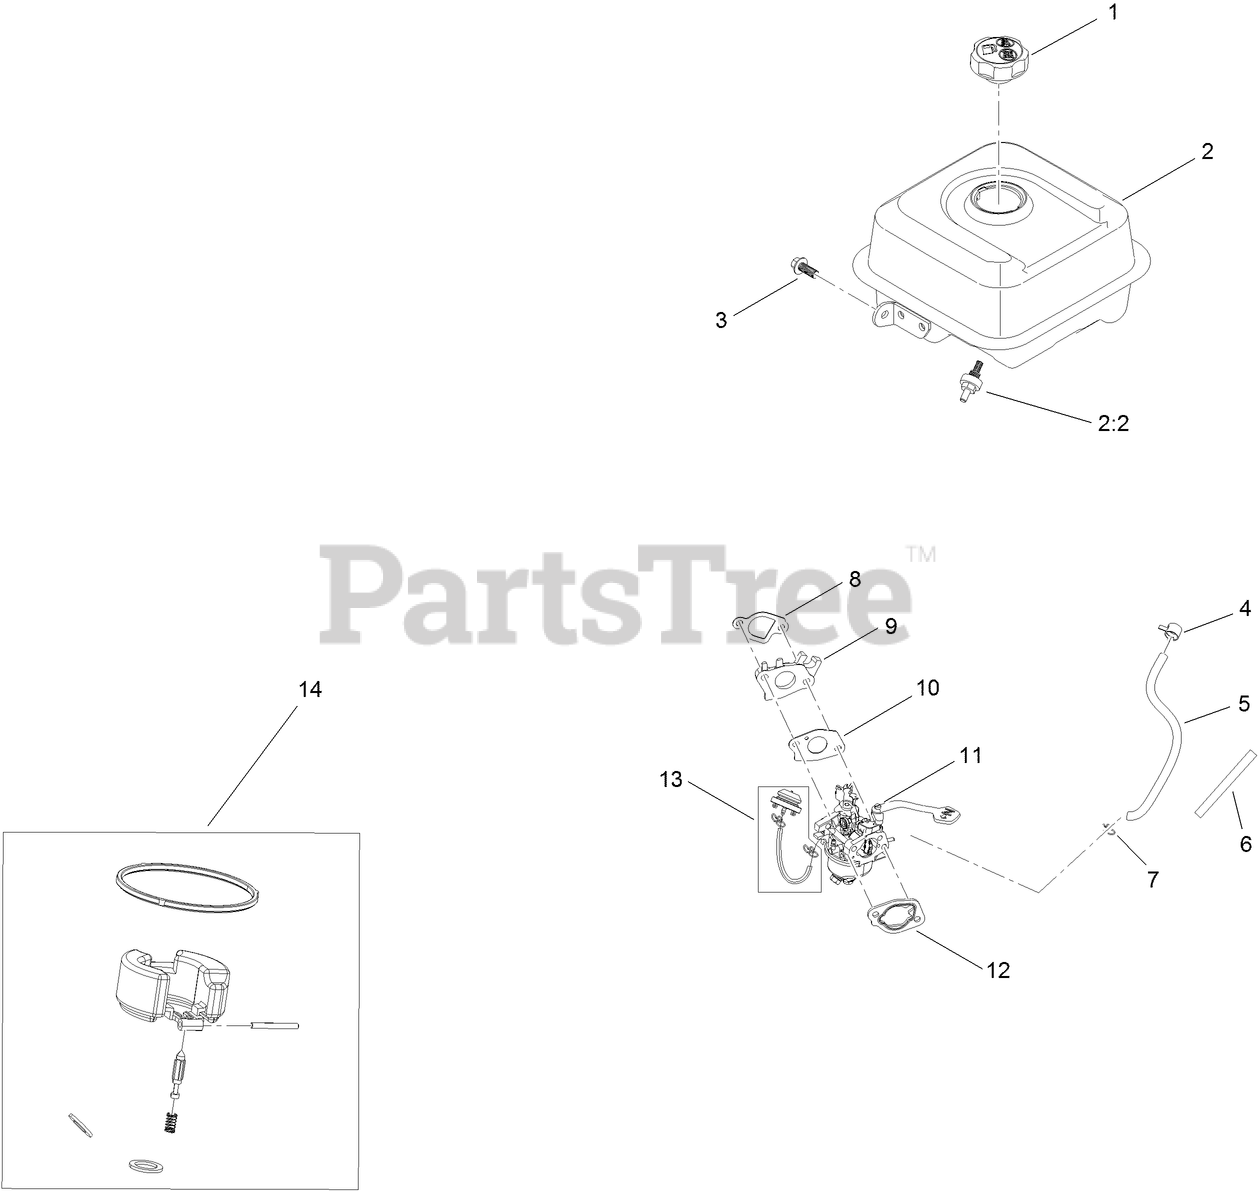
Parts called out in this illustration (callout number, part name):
1	CAP-FUEL (PHASE 3)
2	FUEL TANK AND FILTER ASM
2:2	FILTER-FUEL
3	SCREW-HHF
4	CLAMP-HOSE
5	HOSE-FUEL
6	SLEEVE-ABRASION
7	CLAMP-HOSE
8	GASKET-CARBURETOR
9	INSULATOR-CARBURETOR
10	GASKET-CARBURETOR
11	CARBURETOR ASM
12	GASKET-CARBURETOR
13	PRIMER KIT
14	INTERNAL CARB SERVICE KIT
